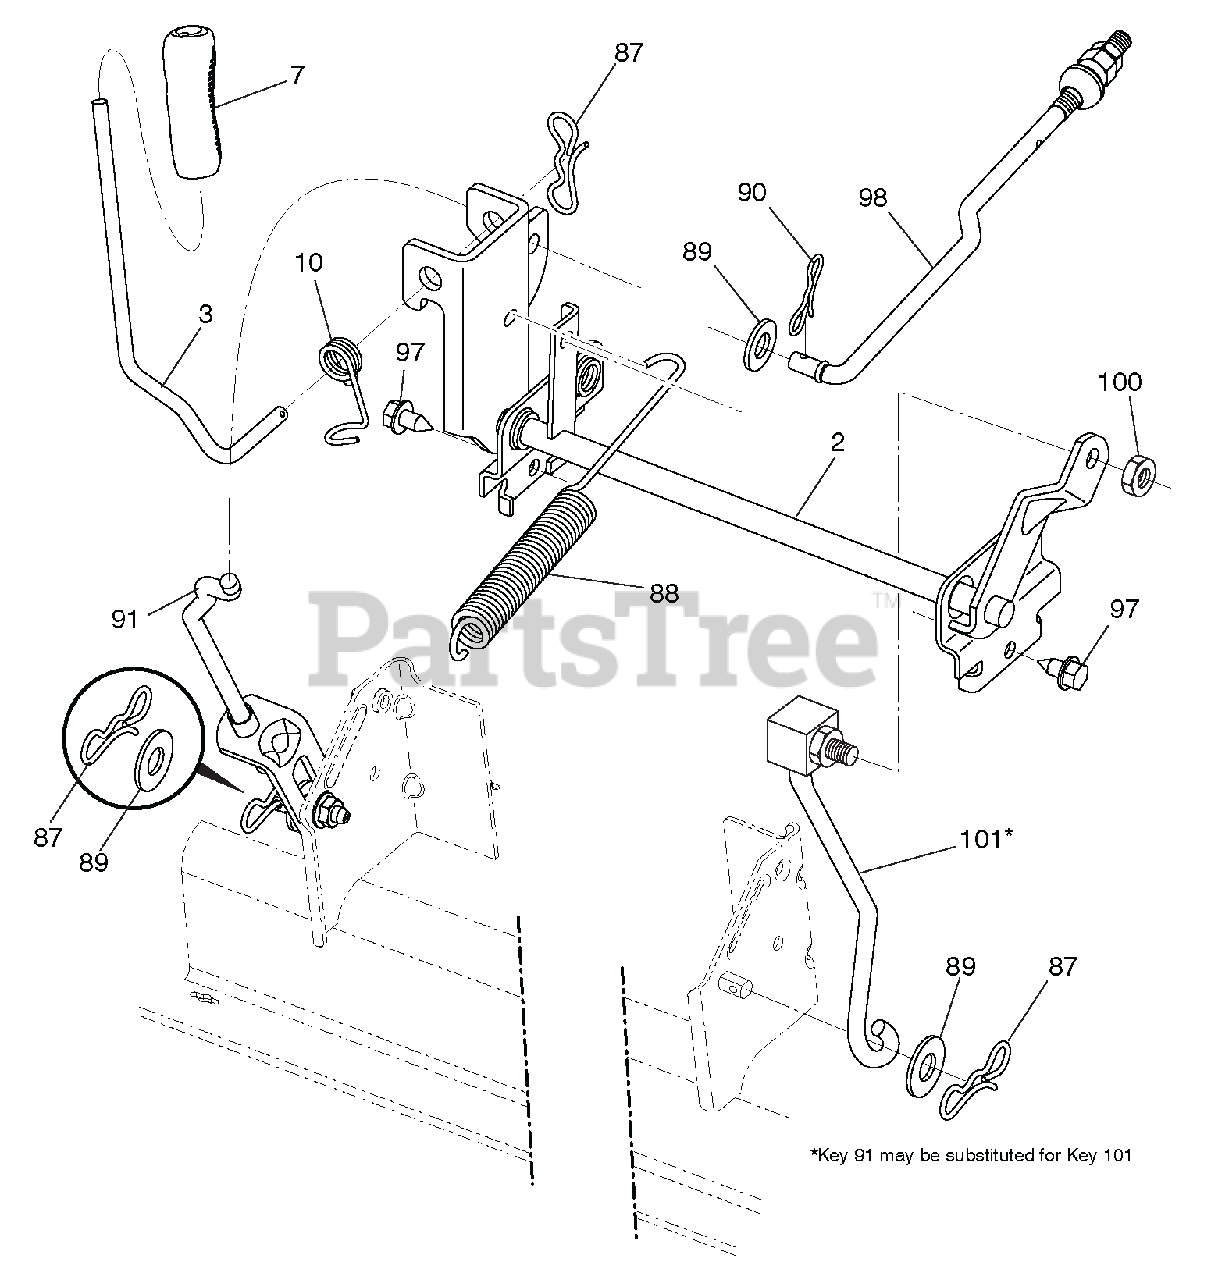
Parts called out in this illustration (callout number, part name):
2	SHAFT ASM., LIFT
3	LEVER.LIFT.HANDLE.LT
7	GRIP LEVER 5625 LD BLACK 428
10	SPRING.TORSION.HANDLE.LIFT
87	PIN.COTTER.7/16.BOW TIE LOCK
88	SPRING.LIFT ASSIST
89	WASHER.CLEAR ZINC
90	PIN.COTTER.5/16.BOW TIE LOCK
91	LINK ASM.LIFT.LH.REAR
97	SCREW.HEXWSH THDR3/8-16X3/4.BL
98	LINK ASM.SUSP.FRONT.MWR.11
100	NUT.CENTERLOCK.3/8-16 UNC.
101	LINK ASM.LIFT.FIXED.38/42/46"
